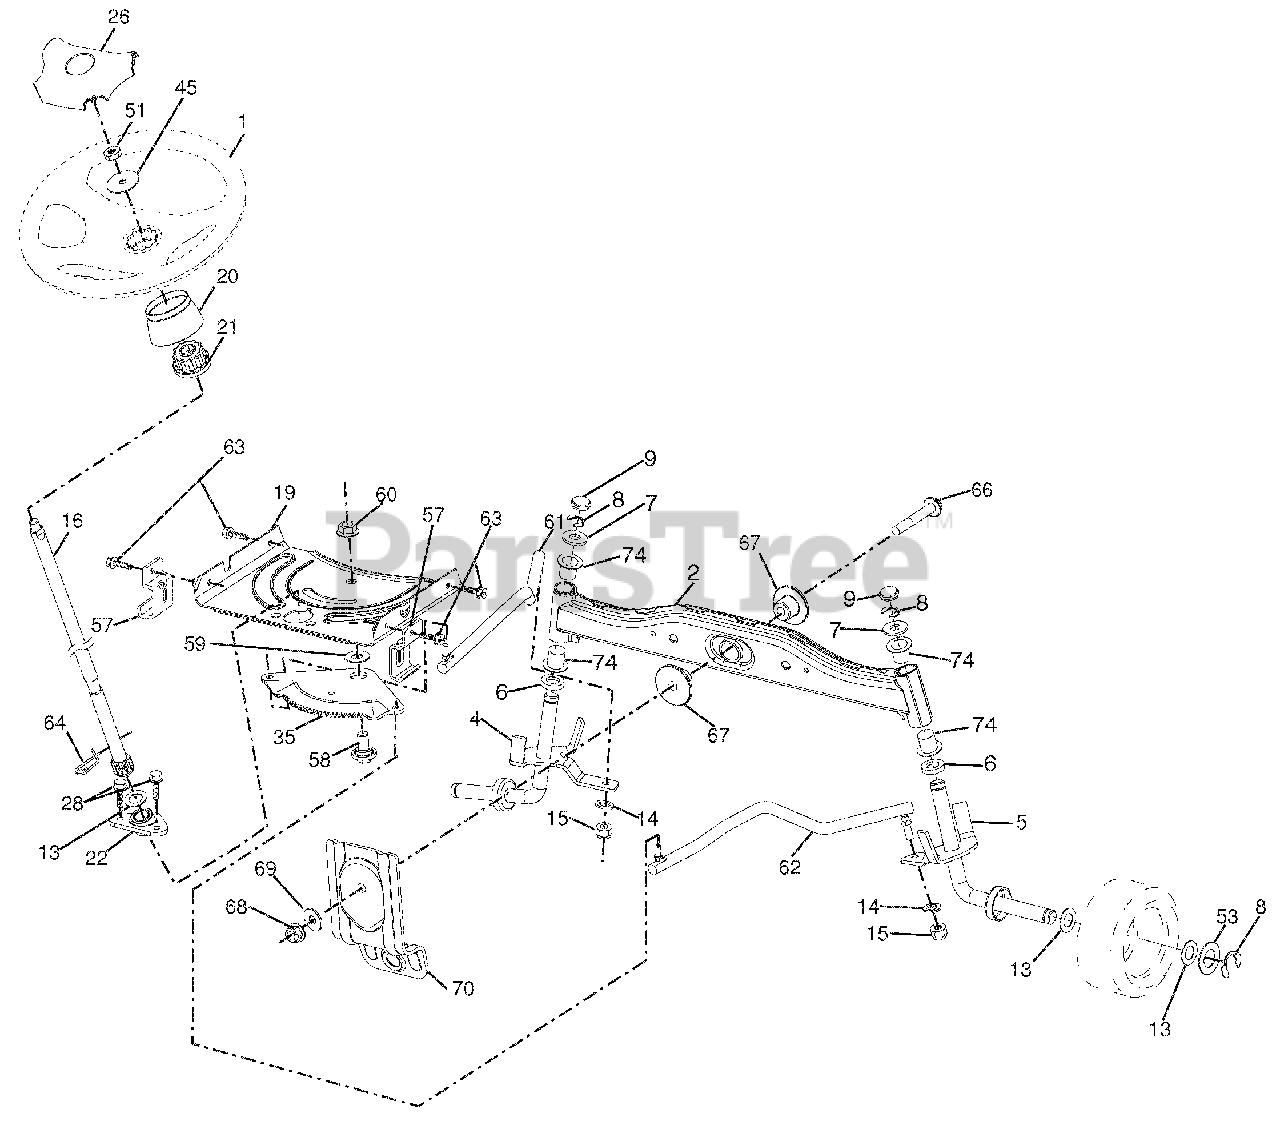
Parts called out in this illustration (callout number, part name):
1	WHEEL.STEERING.HARD RIM.BLACK
2	AXLE ASM.WELDED
4	SPINDLE.WELDED.LH.15"TEX
5	SPINDLE.WELDED.RH.15"TEX
6	WASHER.THRUST..75 X 1.230
7	WASHER.25/32 X 1-5/8 X 16GA.
8	RING.KLIP.#T5304-75
9	CAP.SPINDLE.FR.TOP.BLK.
13	WASHER.25/32 X 1 1/4 X 16 GA.
14	Washer, Lock 3/8
15	NUT.CROWNLOCK.3/8-24
16	SHAFT.STEER.3/4 TEX.NON-PLATED
19	PLATE.STEER.DDL.NLT/NGT
20	BOOT.STEERING.LT.TEX P/L.428
21	ADAPTER.WHEEL.STRG..760
22	STEERING SUPT. LOWER
26	CAP.WHL.STRG.HRS/SRS.BLACK
28	SCREW.HEXWSH THDR3/8-16X3/4.BL
35	GEAR SECTOR.PLATE.DDL.NLT/NGT
45	WASHER.9/16ID X 2-3/8OD.12GZIN
51	NUT.HEX.JAM.TOPLOCK.1/2-20 UNF
53	WASHER.HARDEN..793 X 1.637X060
57	BRACKET.UPSTOP.TEX
58	BOLT.SHOULDER.SECTOR.PIVOT.CFM
59	WASHER.THRUST.SECTOR.STEER.NLT
60	NUT.FLANGE LOCK.5/8-11
61	DRAGLINK.LH.BALLSTUD.DDL.
62	DRAGLINK.RH.BALLSTUD.DDL
63	SCREW.5/16-18X3/4.SMGML.TAP/BL
64	RETAINER.CLIP.SPRING.STEERING
66	BOLT.HEX.FGHD.7/16-14 X 3.SERR
67	BUSHING.PM.FRONT AXLE
68	NUT.LOCK.FLANGE.7/16-14.GR5
69	WASHER.1.5 X .505 X .118
70	BRACKET.DECK.SUSPENSION.FRONT
74	BEARING.COL.STRG.BLK.
